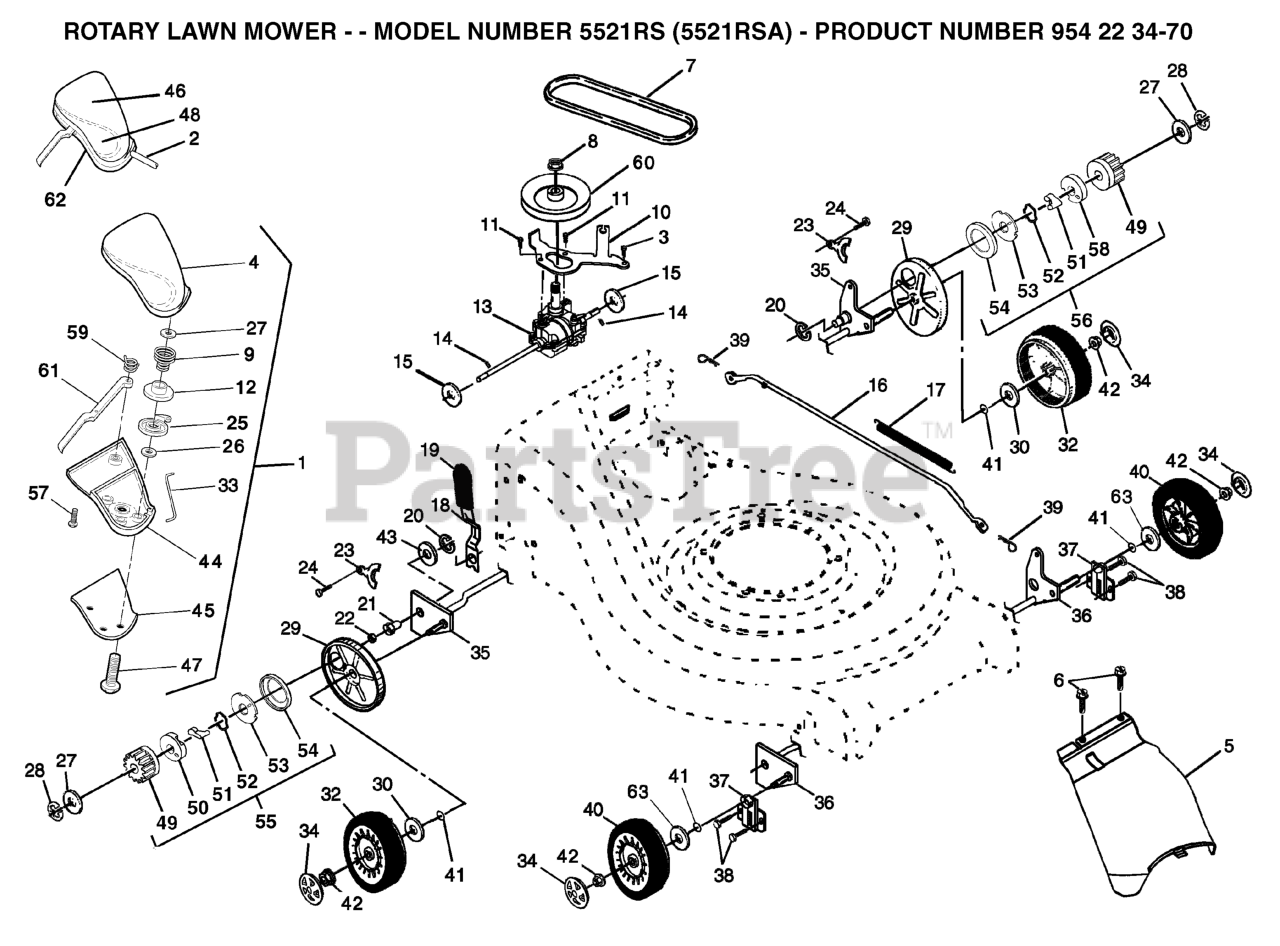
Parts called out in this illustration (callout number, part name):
1	CONTROL.DR.AW.GRY.RWGD.NLA
2	CABLE, DRIVE CONTROL
7	V-BELT
8	FLANGED LOCKNUT 3/8-16 ZINC
9	SPRING, PULLEY ADJUSTER
10	BELT KEEPER BRKT
11	Screw, Hex Washer Head #10-24 x .668
12	PULLEY, SPLIT, UPPER
13	GEARCASE ASSY.
14	PIN.SPRING.THRUST
15	THRUST WASHER
16	ROD CONNECTING
17	SPRING
18	SPRING
19	RP KNOB SELECTOR SPRING
21	RP BEARING SUPPORT
22	BEARING, BALL
23	BRACKET
25	PULLEY, SPLIT, LOWER
26	THRUST WASHER
28	E-RING 7/16 RE
29	DUST COVER, WHEEL
30	WASHER FLUT
32	WHEEL.9X2.PR.LP.RADIAL.BK.BB.3
33	CONNECTOR, LEVER PULLEY
34	HUBCAP
35	SHAFT ASSY
36	SHAFT ASSY
37	RETAINER.FRONT.SHAFT
39	RETAINER CLIP
40	WHEEL ASMBLY FRONT
41	O-RING
42	HEX FLANGE LOCKNT
43	WASHER.ZINC.PLATED
45	PLATE, TRIGGER, AUTO-WALK DRIV
46	DECAL AUTO WALK CONTROL
47	SCREW, PHILLIPS HEAD 10 X 5/8
48	DECAL,DRIVE CONTROL OPERATION
49	GEAR, PINION
50	RETAINER, DRIVE, RH
51	PAWL.DRIVE.21.EZ-WALK
52	SPRING, TORSION
53	DISC.DRIVE.21.EZ-WALK
54	SEAL, FRICTION
55	PINION/PAWL ASSY RH
56	PINION/PAWL ASSY LH
57	SCREW
58	RETAINER.DRIVE.21.EZ-WALK.LT
59	SPRING, RETURN, LEVER
60	PULLEY HALVES
61	LEVER.SHORT.BLUE.HV.
63	WASHER.FLAT.1/2
